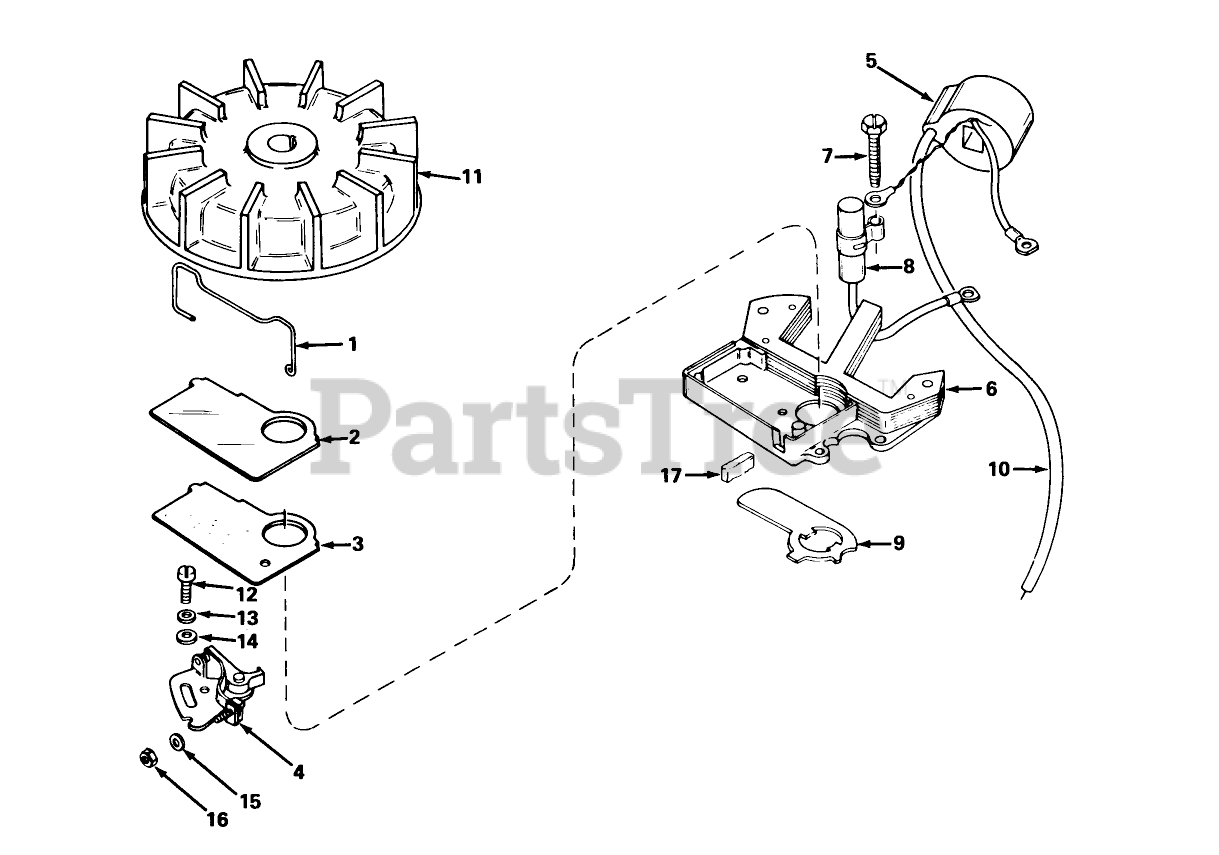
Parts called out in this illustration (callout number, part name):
1	Dust Cover Spring
2	Dust Cover
3	Dust Cover Gasket
4	Hose-Primer 209543
5	Coil Assy.
6	Gasket 209542
7	Condenser Screw
8	Condenser Assy.
9	Sealing Washer
10	STRAP S
11	RETAINER WASHER
12	Fuel Hose
13	Fuel Tank
14	Flatwasher
15	Washer
16	DECAL
17	Cam Felt
